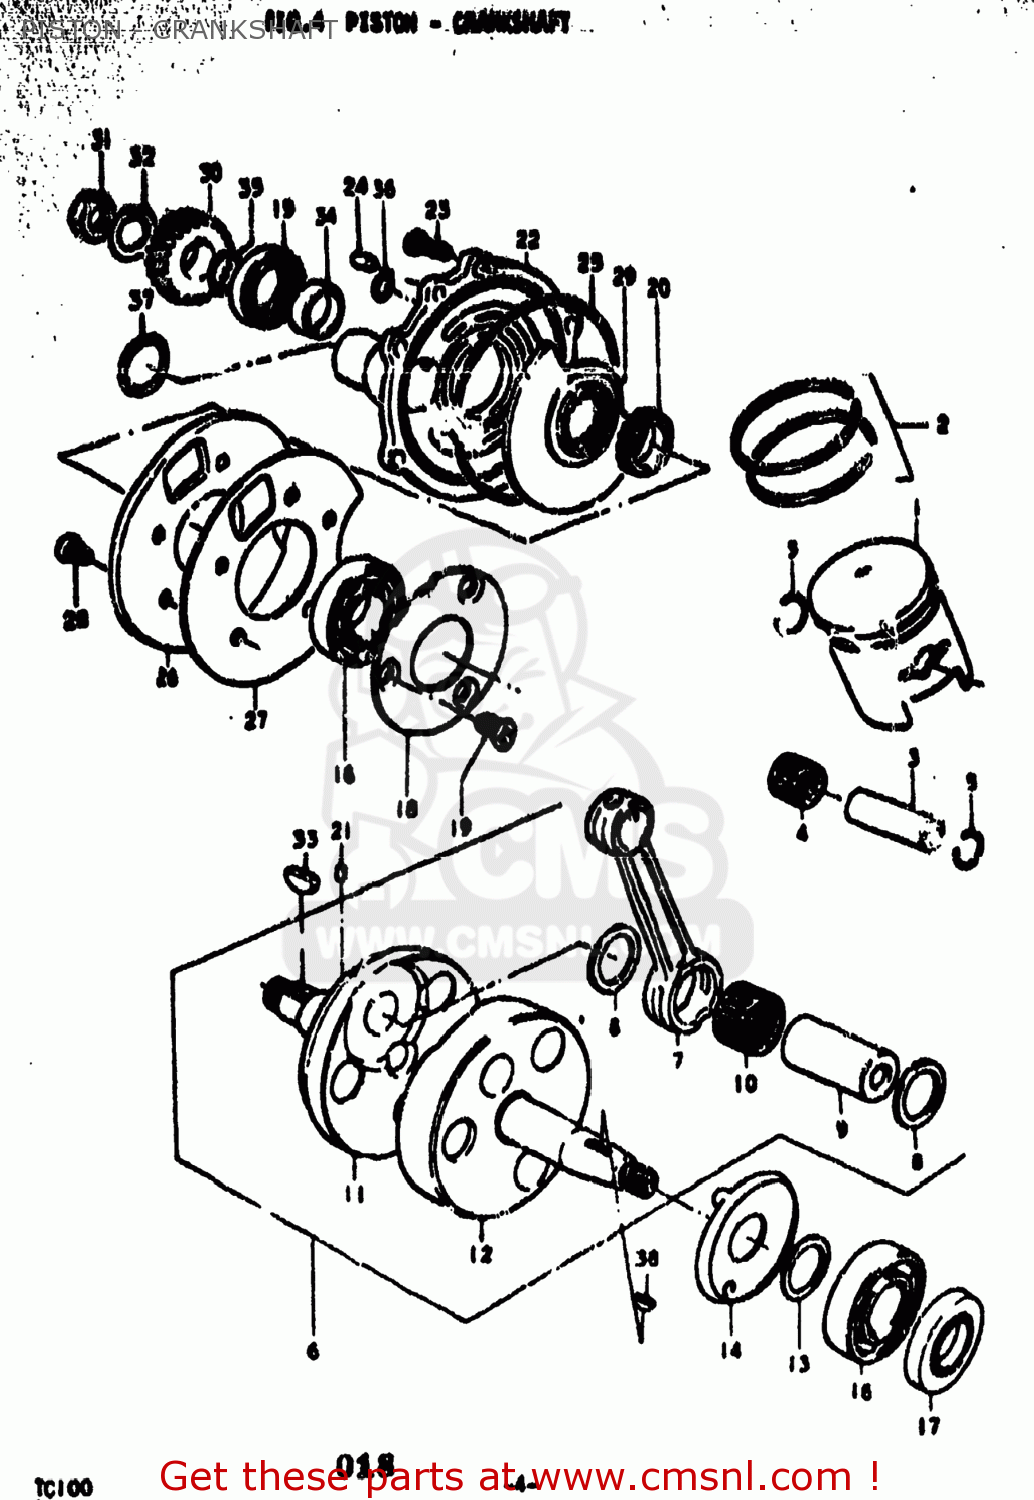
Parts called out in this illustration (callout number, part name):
1	PISTON SET(OS:1.0)
2	RING SET,PISTON
3	PIN,PISTON
4	BEARING
5	RING,SNAP
6	CRANKSHAFT ASSEMBLY
7	ROD,CONNECTING
8	WASHER
9	PIN,CRANK
10	BEARING
11	CRANKSHAFT
12	CRANKSHAFT,LEFT
13	THRUST WASHER
14	PLATE,CRANKSHAFT OIL GUIDE
15	SEAL,OIL(25X40X7)
16	BEARING
17	SEAL,OIL(20X40X7)
18	PLATE
19	SCREW
20	GUIDE,ROTERY VALVE
21	PIN 3X5
22	SEAT,CRANKCASE OUTER VALVE
23	SCREW
24	PIN
25	O RING(D:2,ID:99)
26	SEAT,INNER DISC VALVE
27	GASKET,INNER DISC VALVE (NAS)
28	SCREW
29	VALVE,CRANKSHAFT
30	GEAR,PRIMARY DRIVE
31	NUT
32	WASHER
33	KEY 4MM
34	SPACER
35	O-RING
36	O RING(D:2.5,ID:7.5)
37	O RING(D:3.5,ID:25.7)
38	KEY
